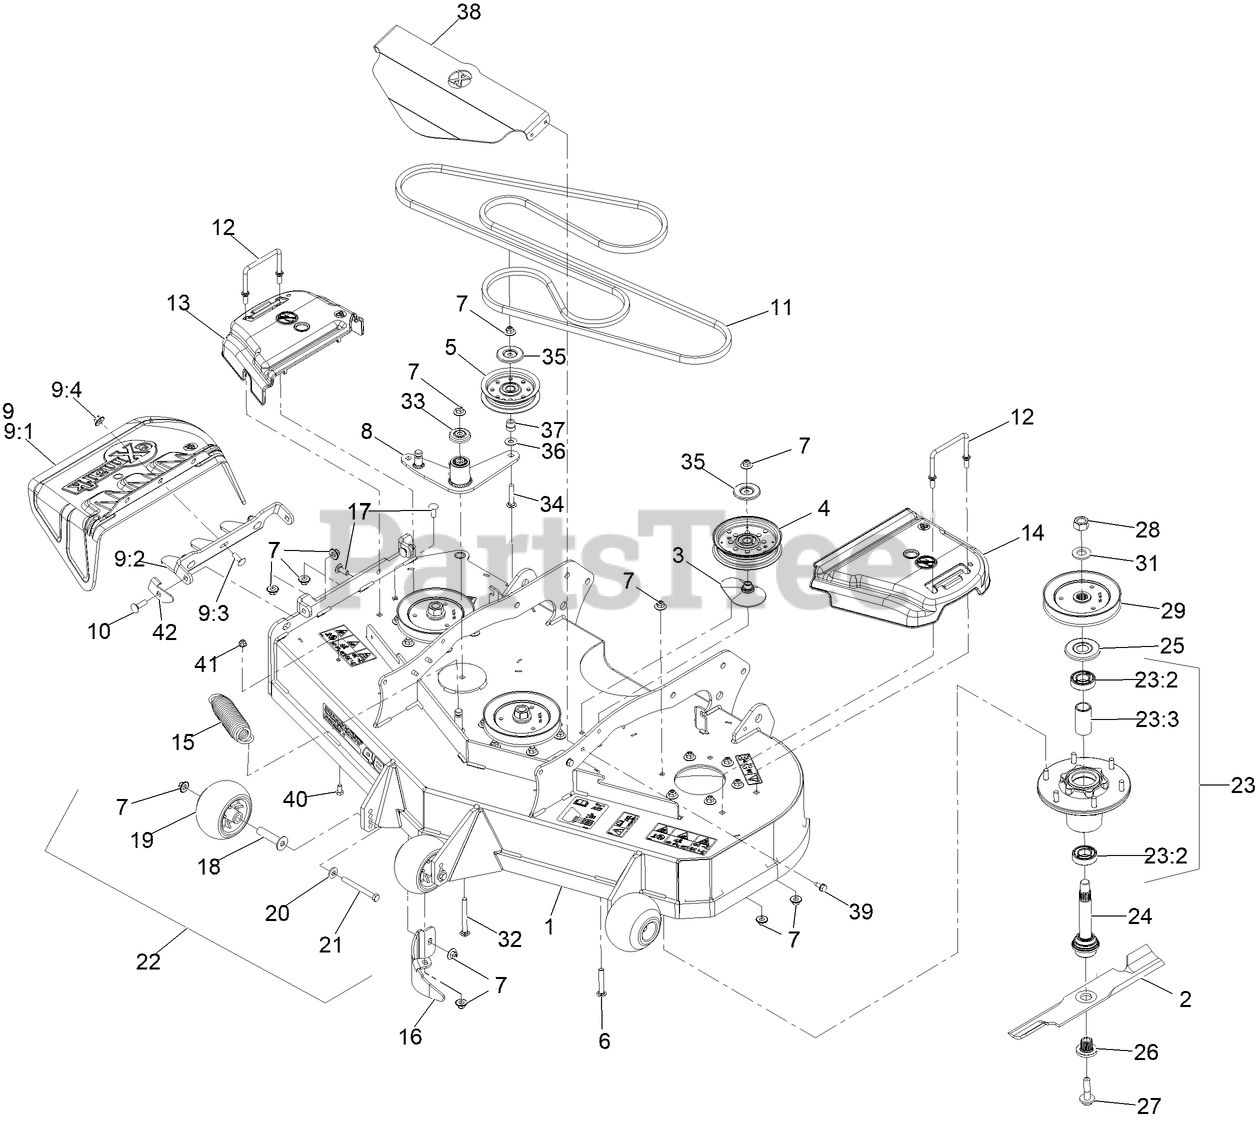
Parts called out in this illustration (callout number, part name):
1	ASM-DECK W/DECALS 484
3	SPACER-PULLEY
4	PULLEY-IDLER, FLAT
6	SCREW-CARR
7	Nut-Nyloc 3/8-16 Flg
8	IDLER ARM ASM W/BEARINGS
9	ASM,DISCHARGE CHUTE
9:1	CHUTE,DISCHARGE
9:2	BRACKET,DISCHARGE CHUTE
9:3	SCREW-CARR
9:4	Nut-Nyloc 3/8-16 Flg
10	BOLT-CARR
11	BELT-B147.4
12	WIREFORM-COVER
13	COVER-BELT, RH
14	COVER-BELT, LH
15	SPRING-EXTENSION
16	BAFFLE-DOGLEG,LZS LZX VT48
17	SCREW-CARR
18	AXLE, ROLLER
19	ROLLER-SCALP, ANTI
20	WASHER-BELLEVILLE
21	SCREW-HH 3/8-16 X 3 3/4 GR 8
22	KIT, ANTI-SCALP ROLLER
23	ASM-CUTTER HSG WITH BEARINGS
23:2	BEARING-BALL
23:3	SPACER-BEARING
24	ASM-SPINDLE AND SEAL
25	GUARD-BEARING, TOP
26	BUSHING,SPLINED
27	SCREW,SEMS 1/2-20 X 2.19
28	NUT-HEX
29	SHEAVE,BLADE DRIVE 5.90
32	SCREW-CARR
33	GUARD-TOP
34	SCREW-CARR
35	SHIELD-DUST
36	WASHER-FLAT
37	BUSHING,IDLER
38	Guard-Front Deck
39	SCREW-THD ROLL, HWH
40	SCREW-HH
41	NUT-HF, NI
42	STOP-DISCHARGE CHUTE
